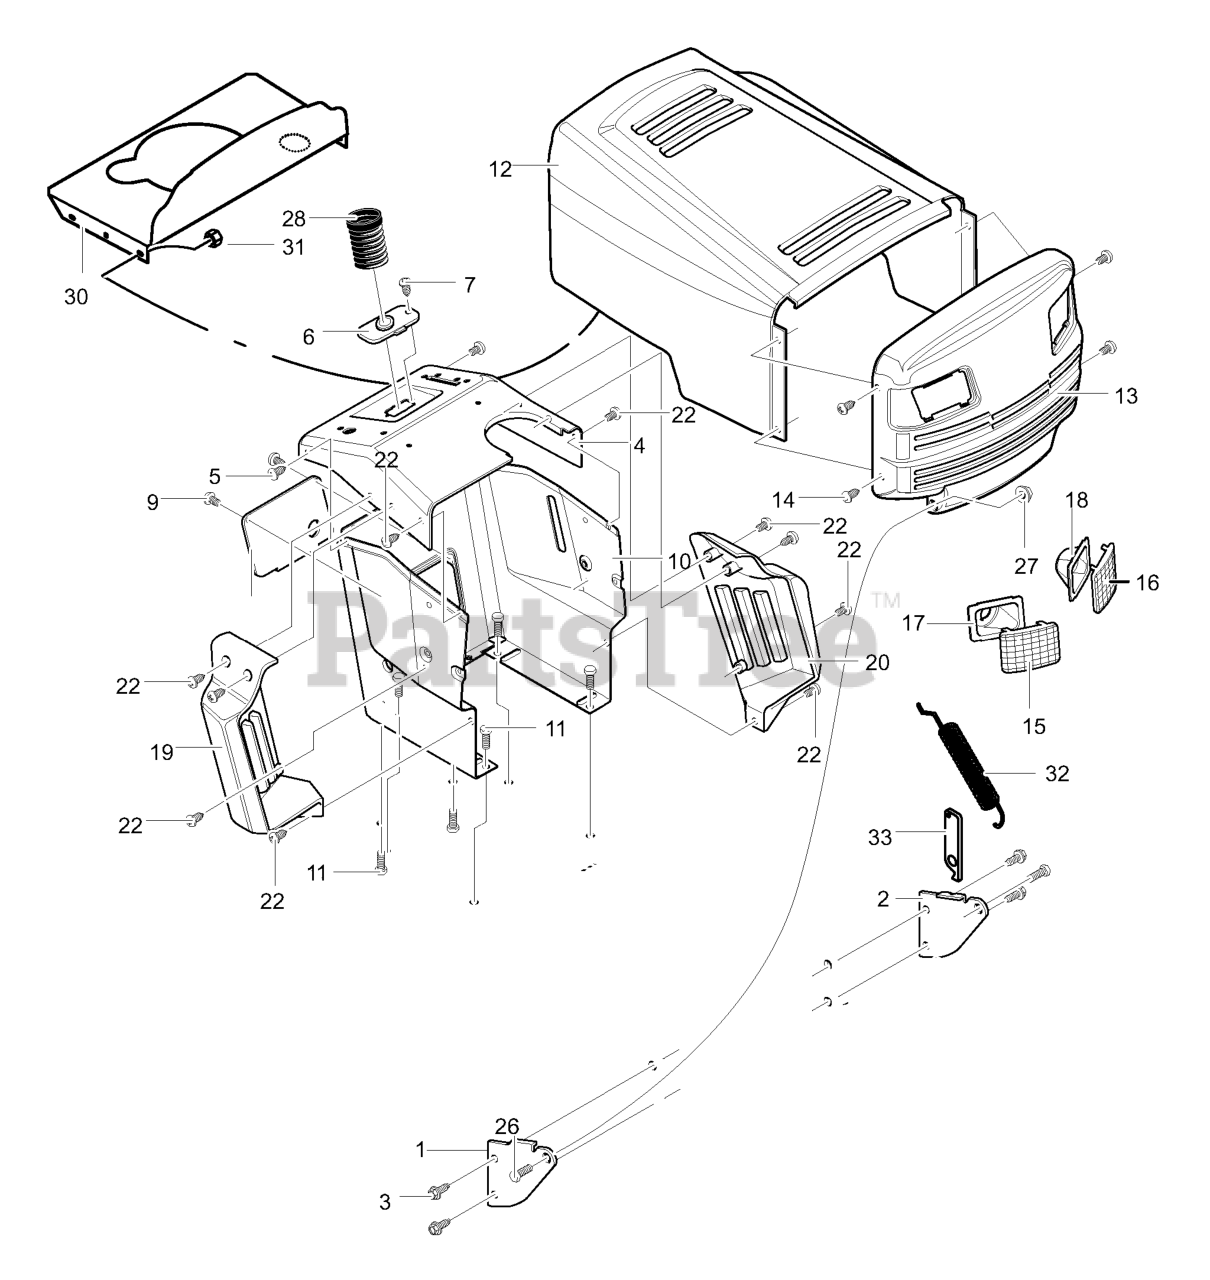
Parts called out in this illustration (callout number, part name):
1	SUPPORT, GRILLE RH
2	SUPPORT, GRILLE LH
3	SCREW, 5/16-18 x .75 HHWATAPSGIBP
5	SCREW, 10-24X.500TRSEG
6	STEERING BRACKET
7	SCREW, 1/4-20X.50WAHHTAP
8	PANEL, ACCESS W/BUZZER
9	SCREW, 10-24X.500TRSEG
10	DASH SUPPORT
11	SCREW, 5/16-18 x .75 HHWATAPSGIBP
14	SCREW, 10-24X.500TRSEG
15	LENS, TWIN RH
16	LENS, TWIN LH
17	REFLECTOR, RH
18	REFLECTOR, LH
19	PANEL, SIDE RH
20	PANEL, SIDE LH
22	SCREW, 10-24X.500TRSEG
26	BOLT, SHOULDER .375
27	NUT, 3/8-16 HWDFLLK MACK
28	BELLOWS-STEERING POST
29	PAD, ADHESIVE
31	NUT, 1/4-20 HEXNYL
32	SPRING, EXT. 5.13LG
33	BRACKET, HOOD
